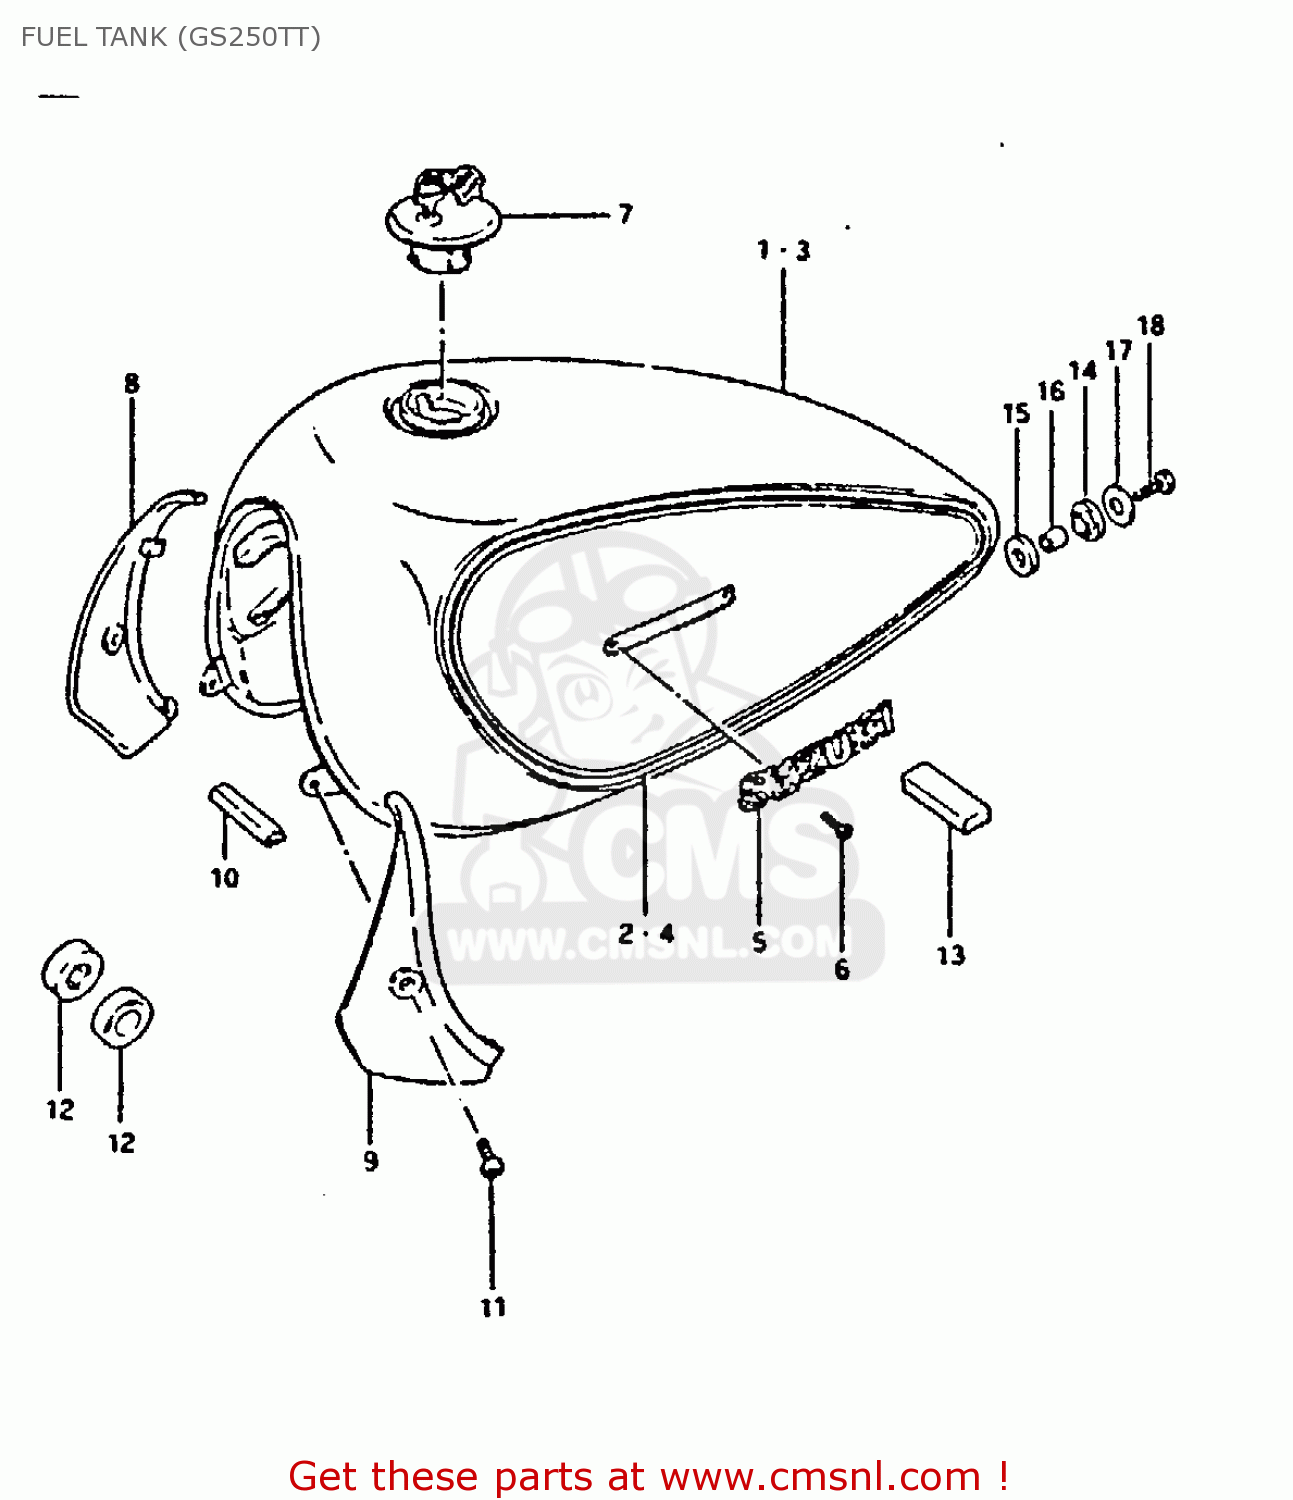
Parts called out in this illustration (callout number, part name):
1	TANK ASSEMBLY,FUEL
2	TAPE SET,FUEL TANK
3	TANK ASSEMBLY,FUEL
4	TAPE SET,FUEL TANK
5	EMBLEM,FUEL TANK
6	SCREW 3X6
7	CAP SET,FUEL TANK
8	COVER,FUEL TANK,FRONT,RIGHT
9	COVER,FUEL TANK,FRONT,LEFT
10	TUBE, FRONT
11	SCREW 6X12
12	CUSHION
13	CUSHION
14	CUSHION
15	CUSHION
16	SPACER(8.5X12X19)
17	WASHER (8.5X29X1.6)
18	BOLT (8X30)
